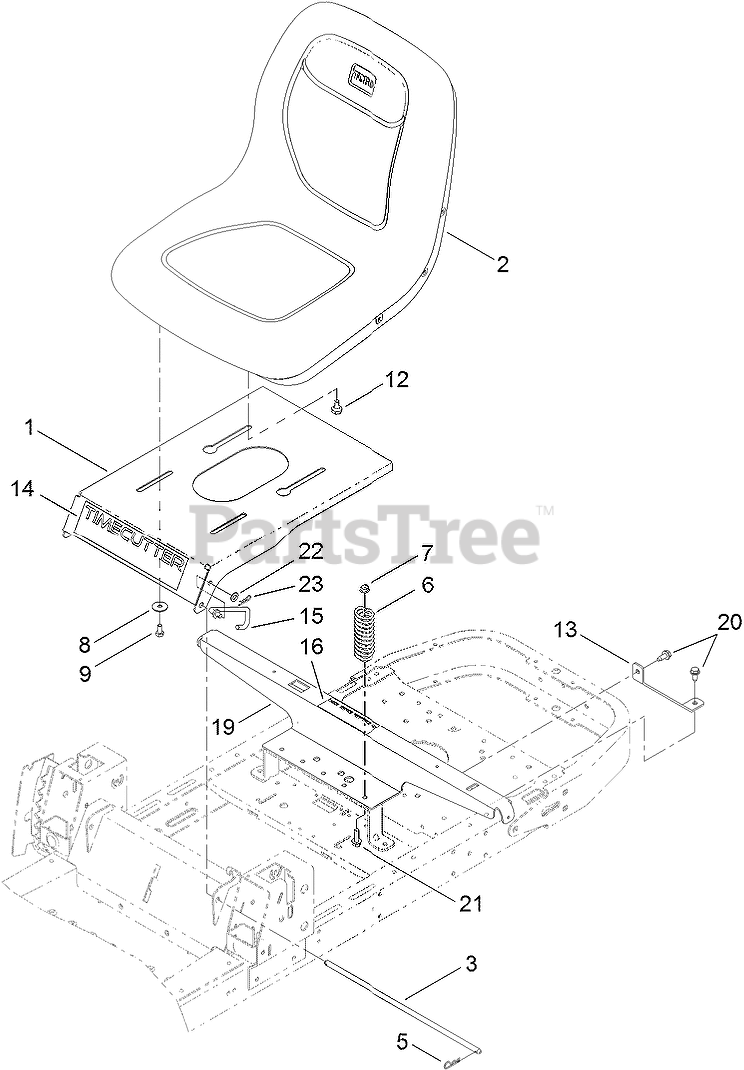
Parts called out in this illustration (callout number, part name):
1	PAN-SEAT
2	SEAT-18 INCH
3	ROD-PIVOT, NARROW
5	PIN-COTTER
6	SPRING-COMPRESSION
7	NUT-HF, NI
8	WASHER-PIVOT
9	SCREW-HH
12	BOLT-SHOULDER
13	SUPPORT-TANK, REAR
14	DECAL-TIMECUTTER
15	STOP-SEAT
16	DECAL-SERVICE, CE
19	SUPPORT-POD
20	SCREW-HWHTF
21	SCREW-HHF
22	WASHER-PLAIN
23	PIN-COTTER
